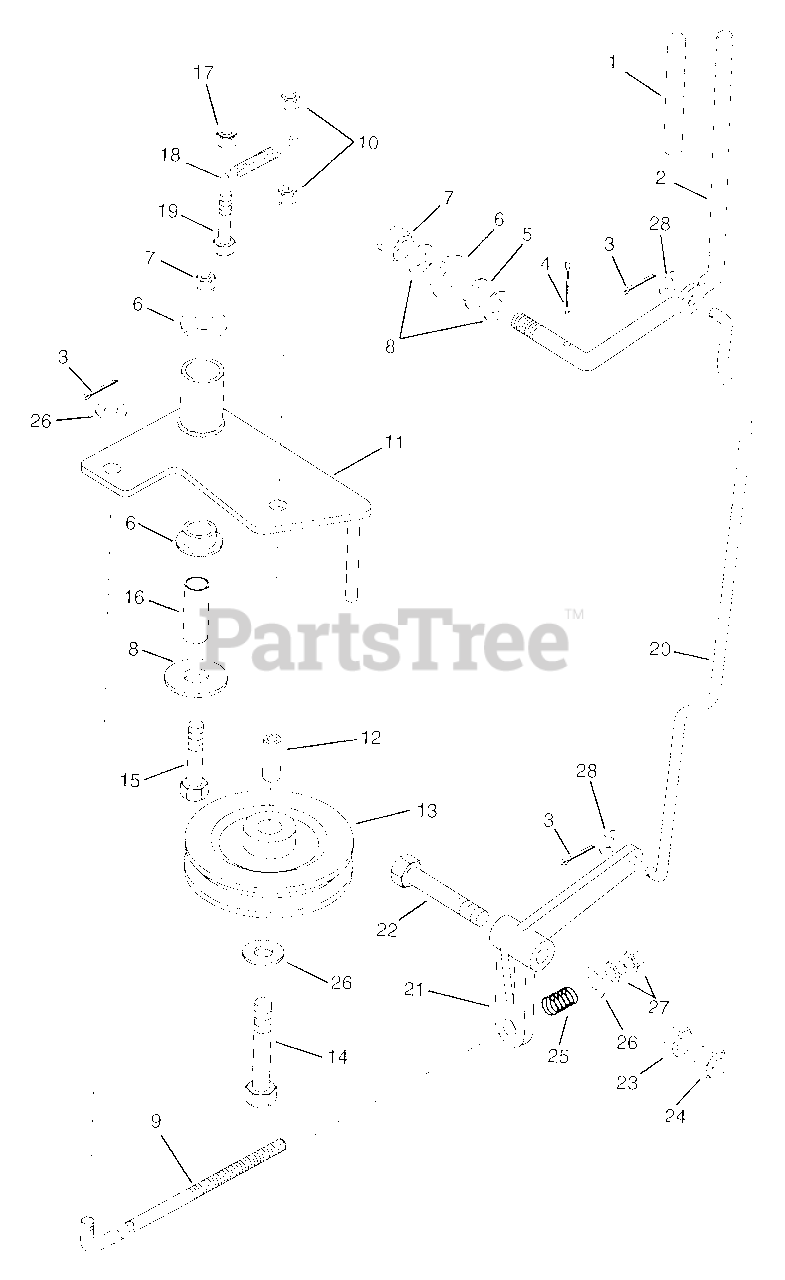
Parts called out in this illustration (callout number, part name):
1	Grip-PTO Lever
2	Lever-PTO Actuating
3	Pin-Cotter .09 x 1.00
4	Pin-Cotter .188 x 1.50
5	Bushing-Flange .515 x .750 x .745 x 1.00
6	Bushing-Flange .762 x 1.0 x .580 x 1.48
7	Nut-Locking-Center .50-13
8	Washer-Flat-Steel .50 x 1.25 x .083
10	Nut-Locking-Center .38-16
11	Declutch Arm-Pro PTO
12	Spacer .391 ID x .75 OD x 1.25
13	Idler-Pulley-Flat 3.25 x .625
14	Bolt-Hex .38-16 x 3.50 Grade 5
15	Bolt-Hex .50-13 x 3.25 Grade 5
16	Bushing for Declutch Arm Pivot
17	Spring-Tension .095 x .85 x 4.38
18	Nut-Locking-Center .31-18
19	Bolt-Hex .31-18X1.25 Grade 5
20	PTO Lever Link Rod, Pro 100
21	Lever-PTO Clutch
22	Bolt-Hex .50-13 x 2.50 Grade 5
23	Nut-Hex .50-13
24	Nut-Locking-Center .50-13
25	Spring-Compression .125 x .78 x 1.00
26	Washer-Flat-Steel .406 x .812 x .065
27	Nut-Hex .38-16
28	Washer-Flat-Steel .344 x .688 x .065
